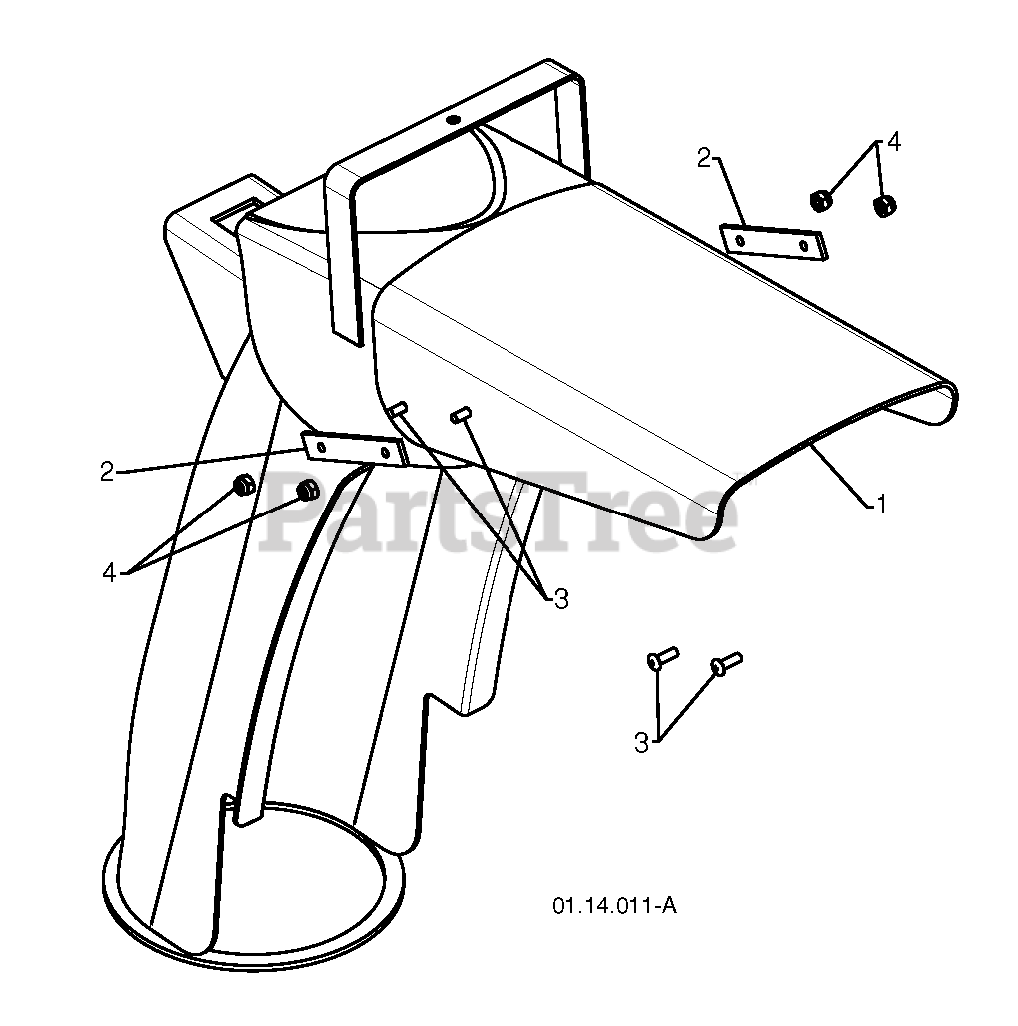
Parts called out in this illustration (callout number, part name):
1	SHIELD.DEFLECTOR.BLACK.SNOW
2	STRAP.DEFLECTOR.SHEILD
3	SCREW.#8.MACH
4	NUT.HEX.#8
